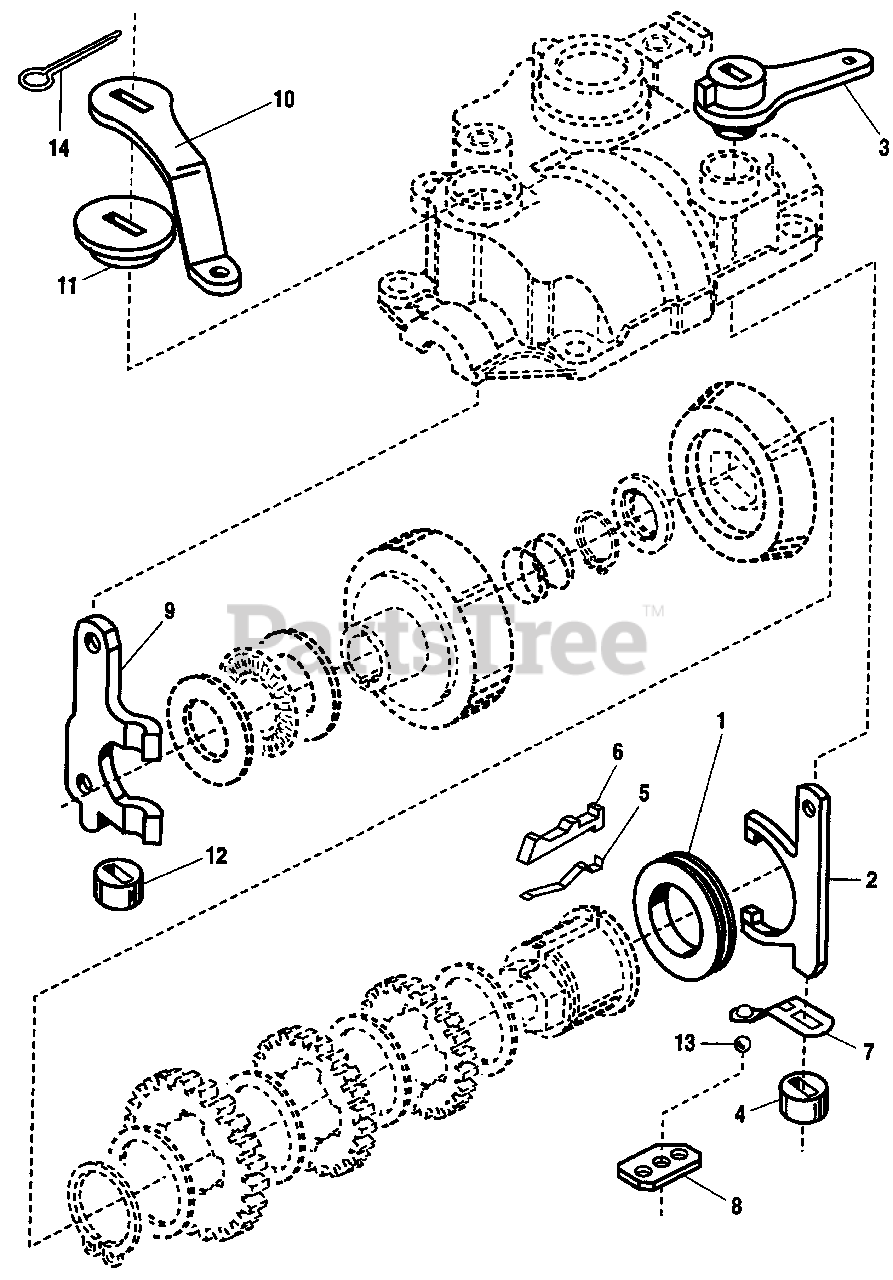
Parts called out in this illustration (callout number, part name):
1	COLLAR, Sliding
2	FORK, Shift
4	SUPPORT, Fork
5	SPRING, Shift
9	FORK, Clutch
10	ARM, Clutch
11	SUPPORT, Upper Clutch
12	SUPPORT, Fork
14	PIN, Cotter
